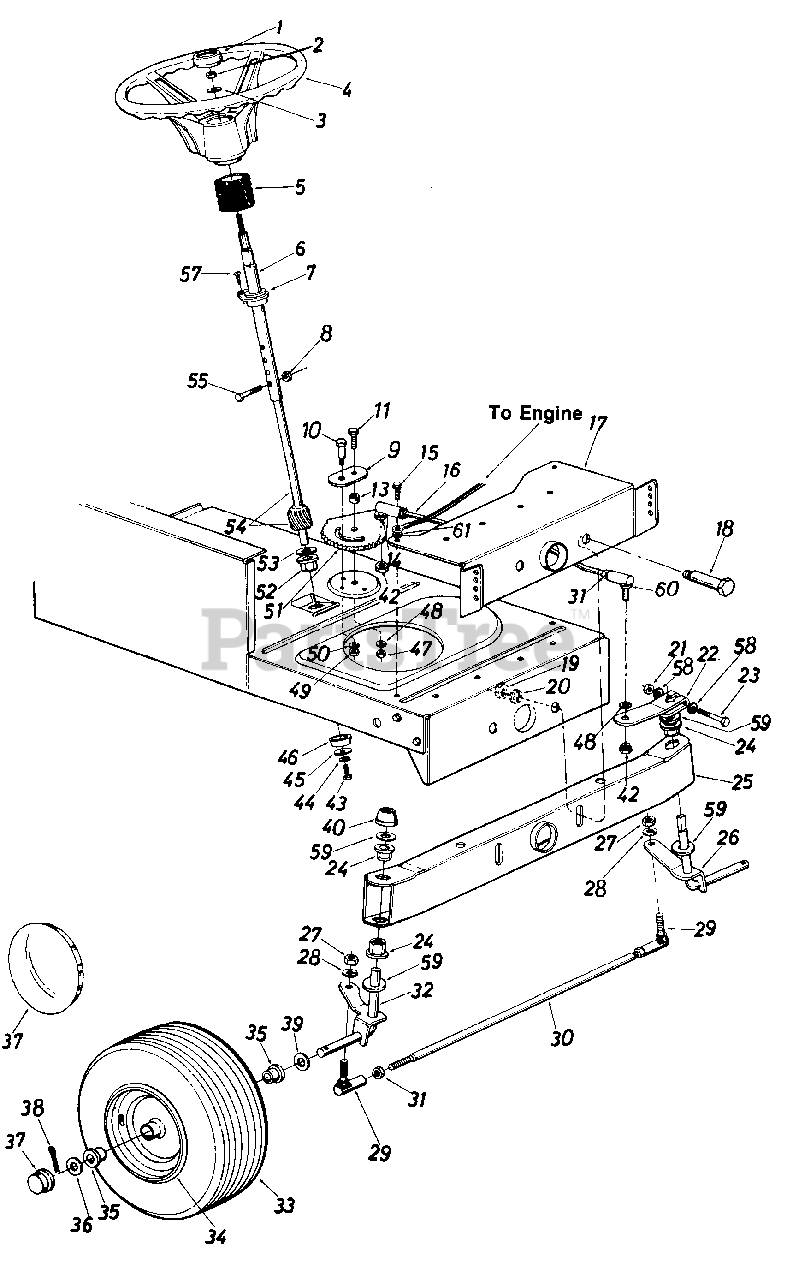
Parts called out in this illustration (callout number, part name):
1	Steering Wheel Cap
2	Hex L-Nut 5/16-24 Thd.
3	Belleville Wash. .345" I.D.
4	Steering Wheel (3 Spoke)
5	Steering Bellow-4.5"
6	Steering Column Ass'y.
7	Flange Bearing .890 I.D. x 1.36 O.D.
8	Hex L-Nut 1/4-20 Thd.
9	Retainer Plate
10	Shoulder Bolt .437" Dia. x .35 Lg. 5/16-18 Thd.
11	Hex Bolt 3/8-24 x 1.0" Lg. (Grade 5)
13	Spacer .380" I.D. x .625" O.D. x .227
14	L-Wash. 3/8" I.D.
15	Hex Wash. Hd. Self-Tap Scr.
16	Steering Drag Link
17	Front Pivot Brkt.
18	Shoulder Bolt .498" Dia. x 2.04 Lg. 3/8-16 Thd.
19	Hex Nut 3/8-16 Thd.
20	L-Wash. 3/8" I.D.
21	Hex Cent. L-Nut 5/16-24 Thd.
22	Steering Arm Front Axle
23	Hex Bolt 5/16-24 x 2.00" Lg. (Grade 5)
24	Hex Flg. Brg. .634 I.D.
26	Front Axle Ass'y.-L. H .
27	Hex Nut 3/8-24 Thd.
28	L-Wash. 3/8" I.D.
29	Ball Joint 3/8-24 Thd.
30	Tie Rod
31	Hex Jam Nut 3/8-24 Thd.
32	Front Axle Ass'y.-R . H .
33	Wheel Ass'y. Comp.
34	Front Wheel Rim Only
35	Bearing
36	Fl-Wash. .635 I.D. x 1.59" O.D.
37	Front Wheel Hub Cap
38	Cotter Pin 1/8" Dia. x 1.25"
39	Fl-Wash. .640" I.D. x 1.24" O.D.
40	Push Cap 5/8" Dia. Rod
42	Hex Jam Nut 3/8-24 Thd.
43	Hex L-8Olt 5/16-18 x .62"
44	L-Wash. 5/16" I.D.
45	Fl-Wash. .33" I.D. x 1.25" O.D.
46	Spacer (Plastic)
47	Hex Nut 3/8-24 Thd.
48	L-Wash. 3/8" I.D.
49	Hex Nut 5/16-18 Thd.
50	L-Wash. 5/16" I.D.
51	Steering Gear Segment
52	Hex Flg. Brg. .634 I.D.
53	Fl-Wash. (Hardened)
54	Steering Shaft Lower
55	Hex Bolt 1/4-20 x 1.25" Lg.
57	Oval Hd. Cr.-Sunk Scr. #10 x 5/8" Lg.
58	Wave-Wash. .32" I.D. x .62" O.D.
59	Fl-Wash. (Hardened)
60	Drag Link Ball Joint 3/8-24 Thd.
61	Ext. L-Wash. 5/16" I.D.
